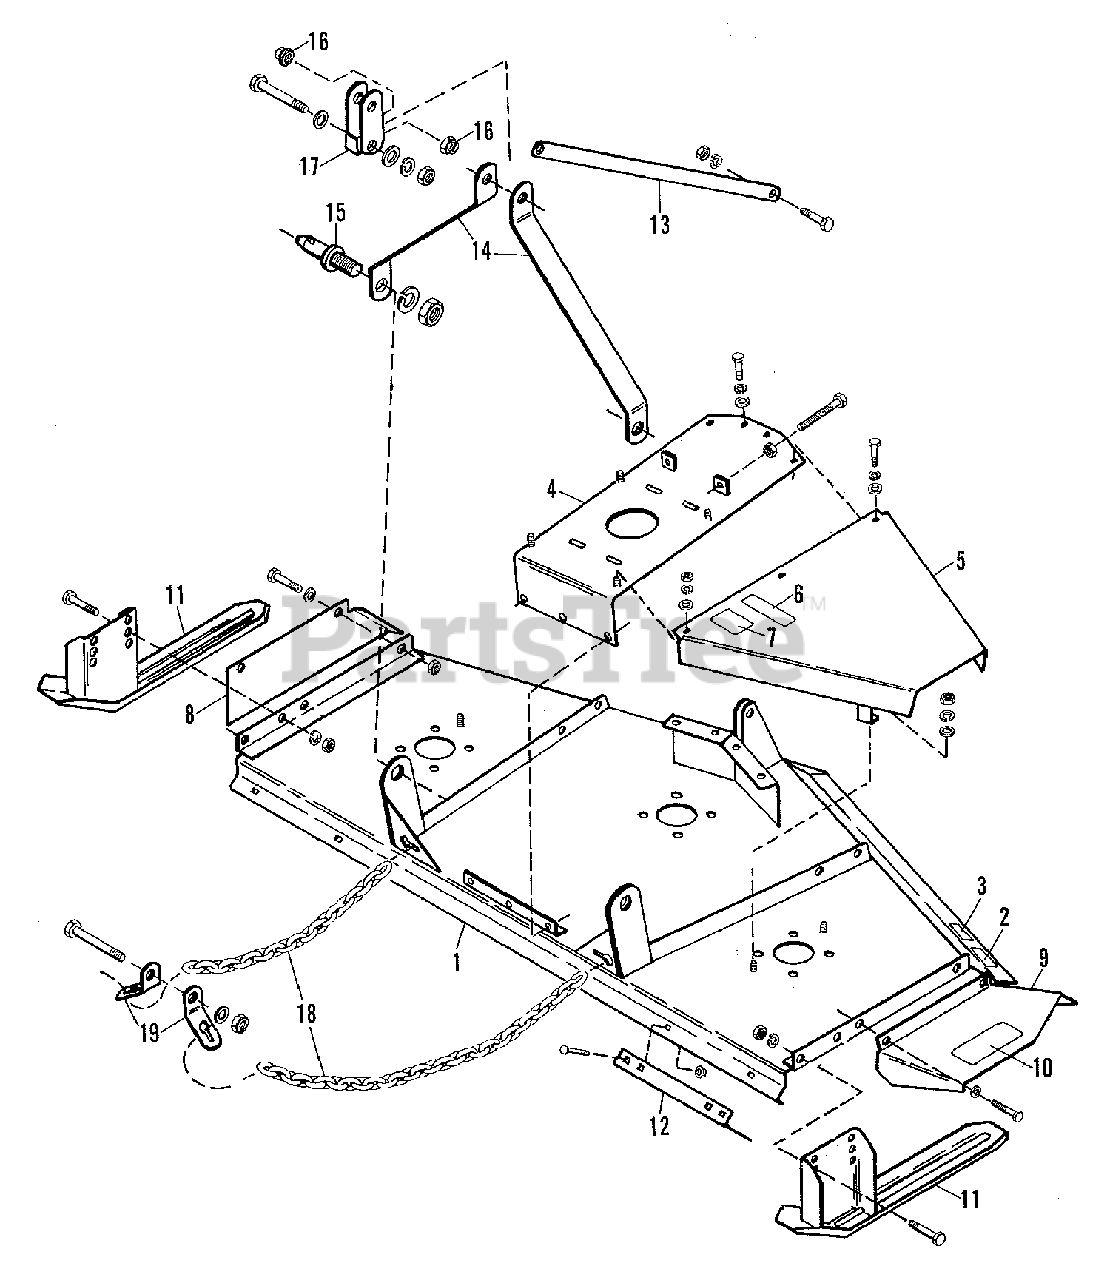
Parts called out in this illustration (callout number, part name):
1	PLATFORM ASSEMBLY
2	DECAL (Allis-Chalmers)
3	DECAL (Model No. 63)
4	PLATE, Mounting
4	CAPSCREW, 3/8NC x 2-1/2, Full Thread
4	CAPSCREW, 3/8NC x 1
4	LOCKWASHER, 3/8
4	WASHER, Plain, 7/16 x 1 x 5/64
5	SHIELD, Belt
5	CAPSCREW, 3/8NC x 1
5	LOCKWASHER, 3/8
5	WASHER, Plain, 7/16 x 1 x 5/64
6	DECAL (Be Careful)
7	DECAL, Danger (Do Not Operate In Transport Position)
8	SHIELD, End, R.H.
8	CAPSCREW, 3/8NC x 1
8	WASHER, Plain, 7/16 x 1 x 5/64
8	NUT, Lock, 3/8NC
9	SHIELD, Discharge, L.H.
9	CAPSCREW, 3/8NC x 1
9	WASHER, Plain, 7/16 x 1 x 5/64
9	NUT, Lock, 3/8NC
10	DECAL, Danger (Discharge Shield)
11	RUNNER, R.H.
11	RUNNER, L.H.
11	CAPSCREW, 1/2NC x 1-1/4
11	LOCKWASHER, 1/2
12	BOLT, Carriage, 3/8NC x 1
12	NUT, Lock, 3/8NC
13	CAPSCREW, 1/2NC x 1-1/2
13	LOCKWASHER, 1/2
15	LOCKWASHER, 7/8
17	CAPSCREW, 1/2NC x 3-1/2
17	WASHER, Plain, 9/16 x 1-3/8 x 12 Ga.
17	LOCKWASHER, 1/2
18	CHAIN, Limit
18	CAPSCREW, 3/8NC x 1
18	WASHER, Plain, 7/16 x 1-1/4 x 11 Ga.
18	LOCKWASHER, 3/8
19	CAPSCREW, 3/4NC x 4
19	LOCKWASHER, 3/4
